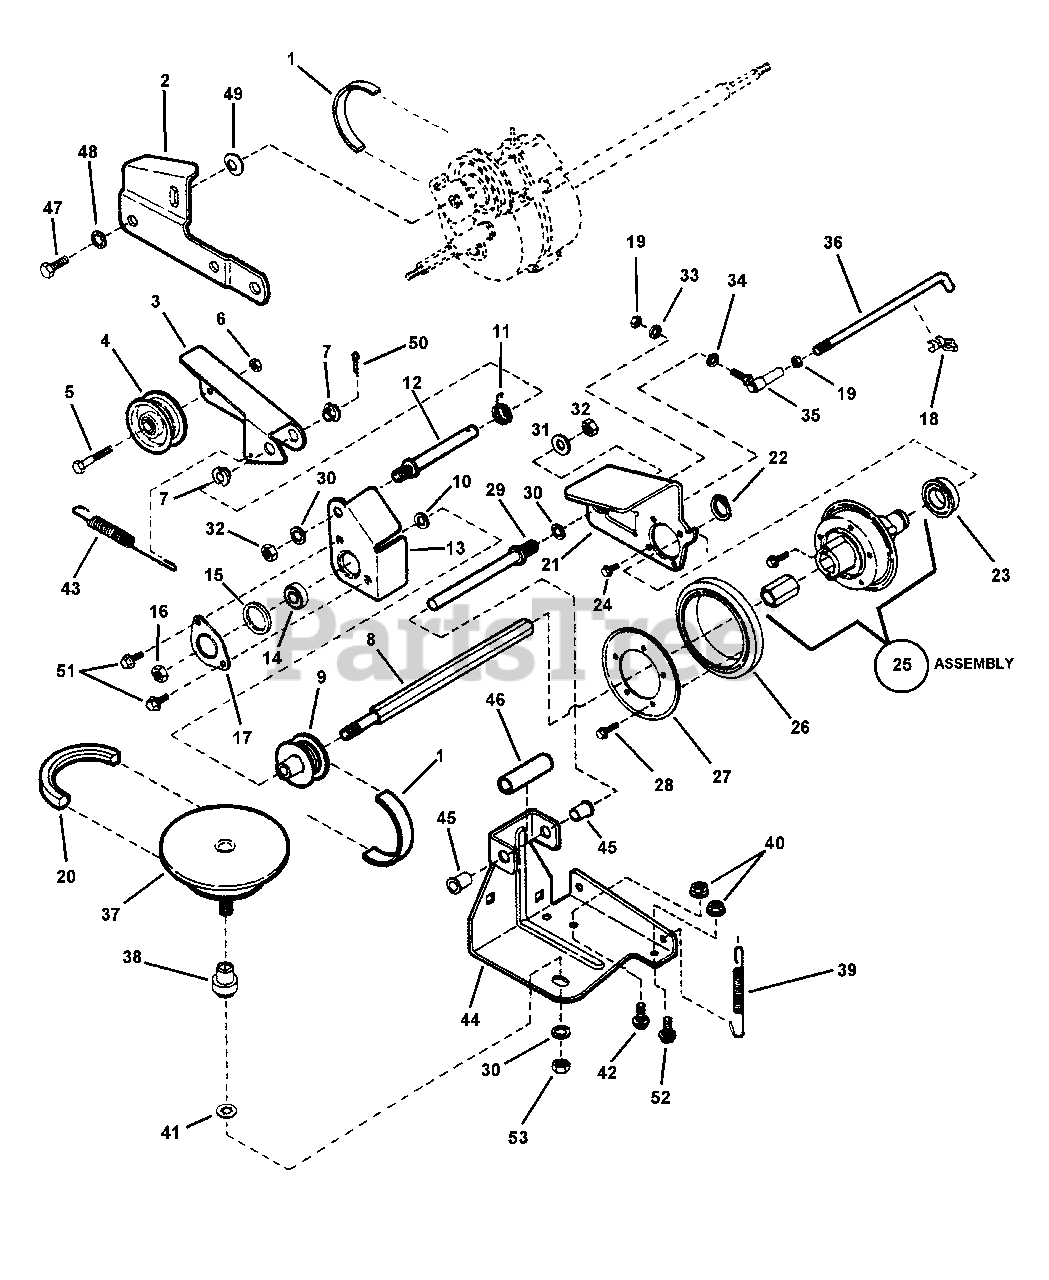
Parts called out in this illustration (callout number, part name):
1	BELT, Poly-Vee
2	LINK, Differential
3	ARM, Clutch Idler
4	PULLEY, Idler
5	SCREW, 1/4-28 x 1-3/8" Hex Head Cap GR5
6	NUT, 1/4-28 Hex Top Lock
7	BUSHING, 3/8" Plastic
8	SHAFT, Hex Drive
9	PULLEY, Poly-Vee
10	WASHER, 3/8" Flat
11	SPRING, Torsion
12	STUD, Idler (3/8-24 thread)
13	HOLDER, Bearing (Inner Half)
14	BEARING, Ball, .38 I.D. Spherical O.D.
15	O-RING
16	NUT, 3/8-24 Hex Center Lock GR5 or B
17	HOLDER, Bearing (Outer Half)
18	CLIP, 1/4" Right Arc (Transfer Rod)
19	NUT, 1/4-28 Hex GR5
20	BELT, Engine Drive 3L (Stretch)
21	PLATE, Thrust
22	RING, 5/8" External Retaining
23	BEARING, Ball
24	SCREW, #10-32 x 1/4" Self-Tap Machine
25	ASSEMBLY, Hub (Includes 11108 Bushing & 90913 Screws)
26	RING, Driven
27	PLATE, Ring Retaining
28	SCREW, #10-24 x 1/2" Hex Washer Self-Tap (Torx)
29	GUIDE, Thrust Plate (3/8-24 thread)
30	WASHER, 3/8" Internal Tooth Lock
31	WASHER, 3/8" Flat
32	NUT, 3/8-24 Hex, GR B
33	NUT, 1/4-28 Hex GR5
34	WASHER, 1/4" Internal Tooth Lock
35	BALL JOINT, 1/4-28
36	LINK, Transfer
37	KIT, Drive Disc Assembly
38	BUSHING
39	SPRING, Wheel Drive
40	NUT, 5/16-18 Hex Flange Lock, GR5
41	RETAINER, 3/8" Bolt
42	BOLT, 5/16-18 x 1/2" Short Neck Carriage GR5
43	SPRING, Clutch
44	BRACKET, Deck
45	BUSHING, Flange, Plastic
46	SPACER
47	SCREW, 5/16-18 x 1/2" Hex Head Cap, GR5
48	WASHER, 5/16" Internal Tooth Lock
49	WASHER, 7/16" Curved Spring
50	PIN, 3/32 x 1/2" Cotter
51	SCREW, 1/4-20 x 1/2" Hex Washer Self-Tap
52	BOLT, 5/16-18 x 5/8" Short Neck Carriage GR5
53	NUT, 3/8-16, Hex, GR 5, Zinc/Clear
